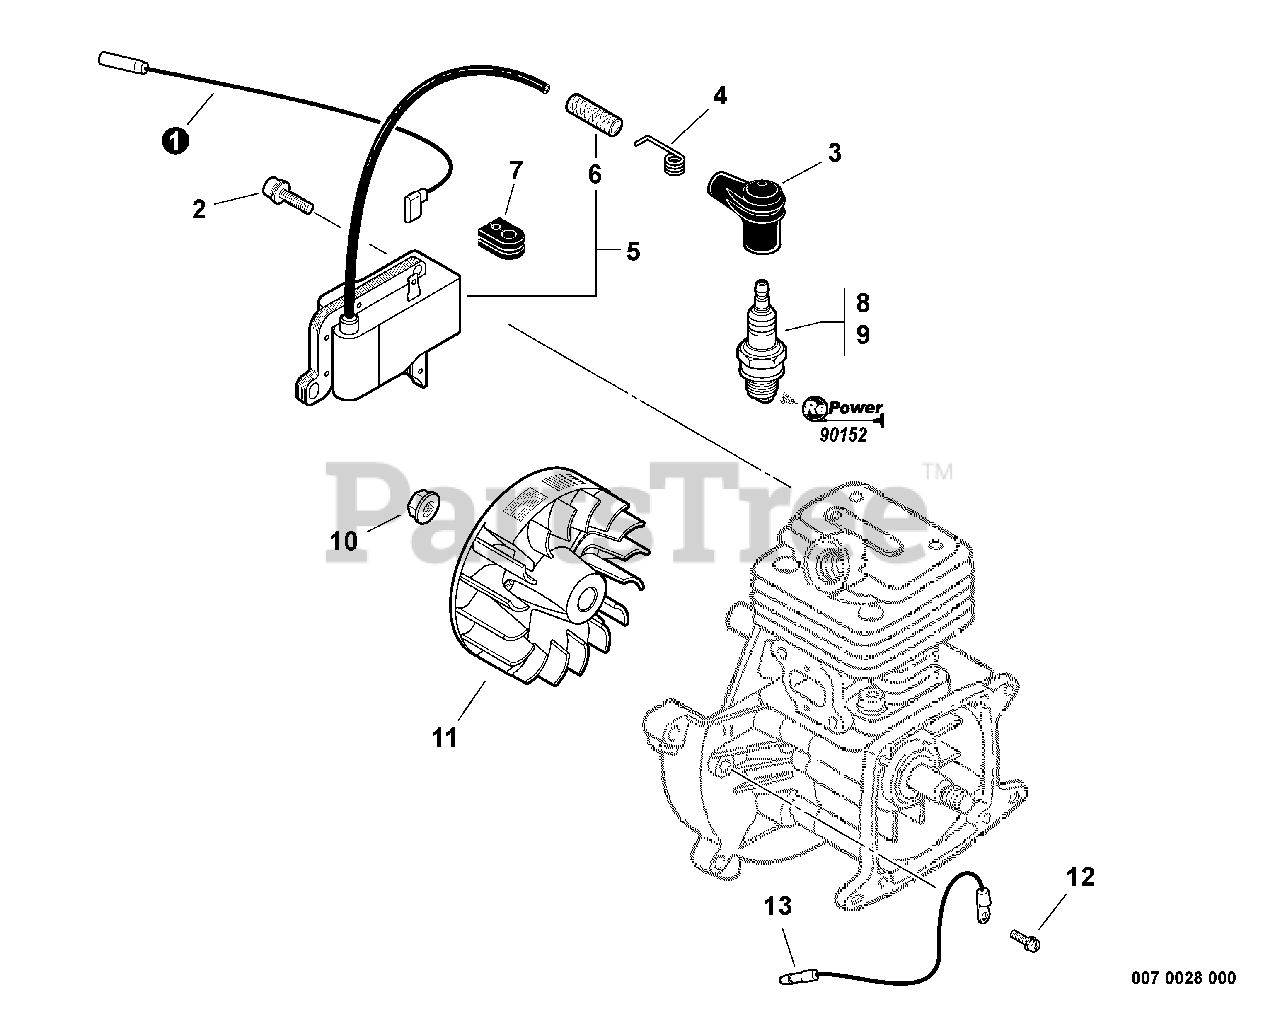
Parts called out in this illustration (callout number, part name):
1	LEAD - IGNITION
2	SCREW - 5X16
3	CAP, SPARK PLUG
4	TERMINAL, SPARK PLUG CAP
5	COIL, IGNITION
6	TUBE, INSULATOR
8	SPARK PLUG -- BPM-8Y
9	SPARK PLUG -- BPMR-8Y
10	NUT - 8 -- FLANGE
11	FLYWHEEL
12	SCREW - 5X10
13	LEAD - GROUND
14	RePower TUNE-UP KIT
